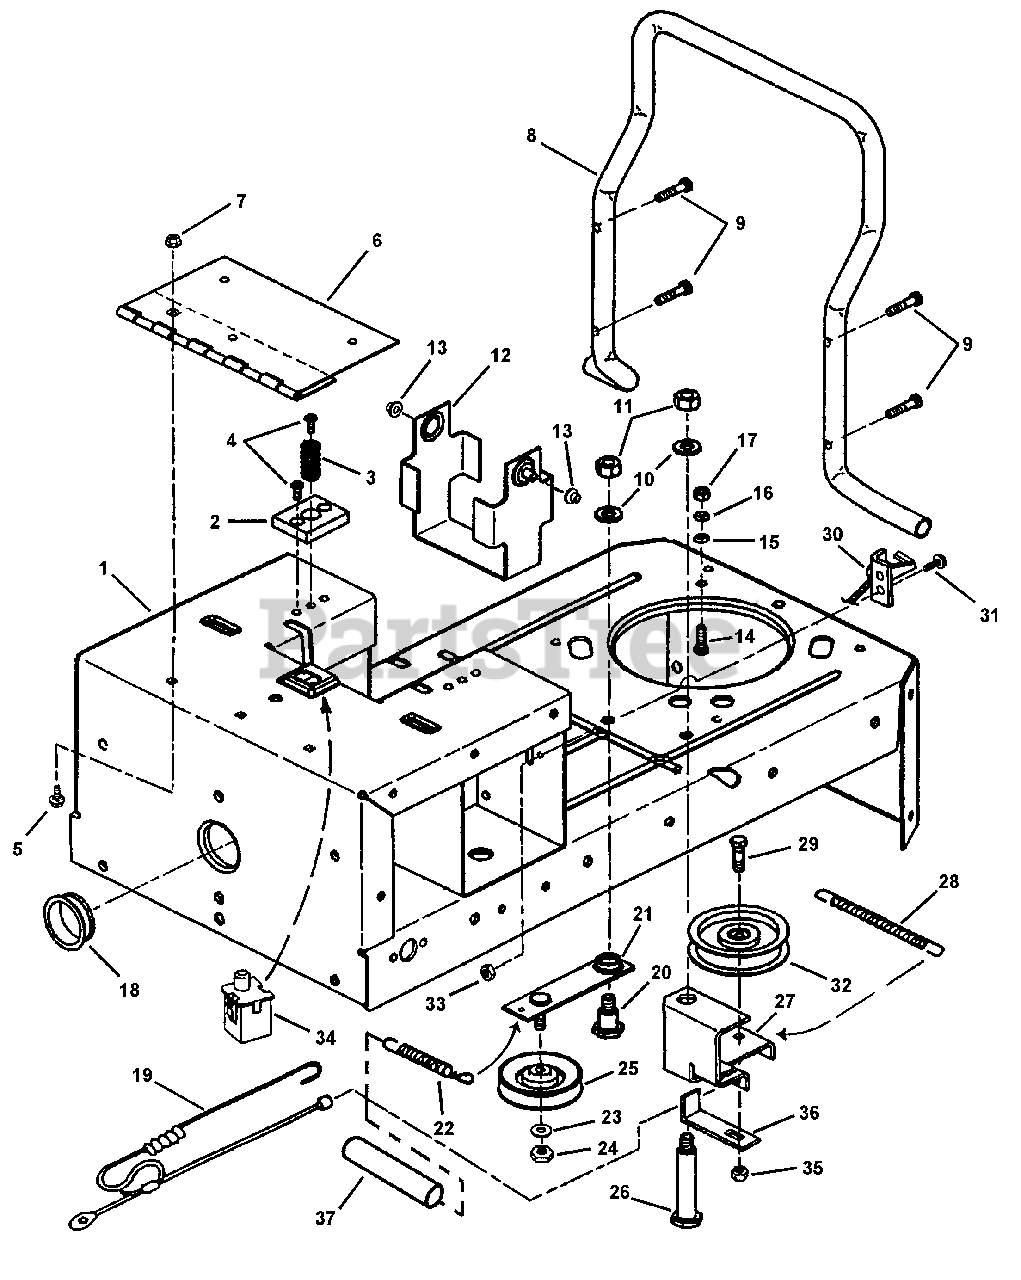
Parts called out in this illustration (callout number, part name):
1	FRAME, Rear
2	CUSHION, Seat Support
3	SPRING, Seat Support
4	SCREW, 1/4-20 x 5/8" Pan Head, Self-Tapping
5	BOLT, 5/16-18 x 1/2" Carriage, Grade 5
6	HINGE, Seat
7	NUT, 5/16-18 Hex Flange Lock, Grade 5
8	BUMPER, Rear
9	SCREW, 5/16-18 x 1-1/2" Self-Tapping
10	WASHER, 1/2" Flat
11	NUT, 1/2-13 Hex, Grade B
12	BRACKET, Battery
13	BUSHING
14	SCREW, 5/16-24 x 1" Hex Head Cap
15	RETAINER, 5/16 Bolt
16	WASHER, 5/16 Split Lock
17	NUT, 5/16-24 Hex, Grade 5
18	GROMMET
19	CABLE, Brake/Clutch
20	BOLT, 1/2-13 x 5/8" Thread, .75 x .788 Shoulder
21	WELDMENT, Primary Idler Arm
22	SPRING, Extension
23	WASHER, 3/8" Flat
24	NUT, 3/8-16 Hex Center Lock, Grade 5
25	PULLEY, Idler 3.50
26	BOLT, 1/2-13 x 5/8" Thread, .75 x 3.23 Shoulder
27	BRACKET, Hydraulic Idler
28	SPRING, 3/4" Extension
29	SCREW, 3/8-16 x 1-3/4" Hex Head Cap, Grade 5
30	CABLE, Hydro Release Valve
31	SCREW, #10-32 x 5/8" Hex Washer Head, Machine
32	IDLER, 4.12 Flat
33	NUT, #10-32 Hex Nyloc
34	SWITCH, Seat
35	NUT, 3/8-16 Hex Center Lock, Grade B or 5
36	GUIDE, Belt
37	COVER, Spring
